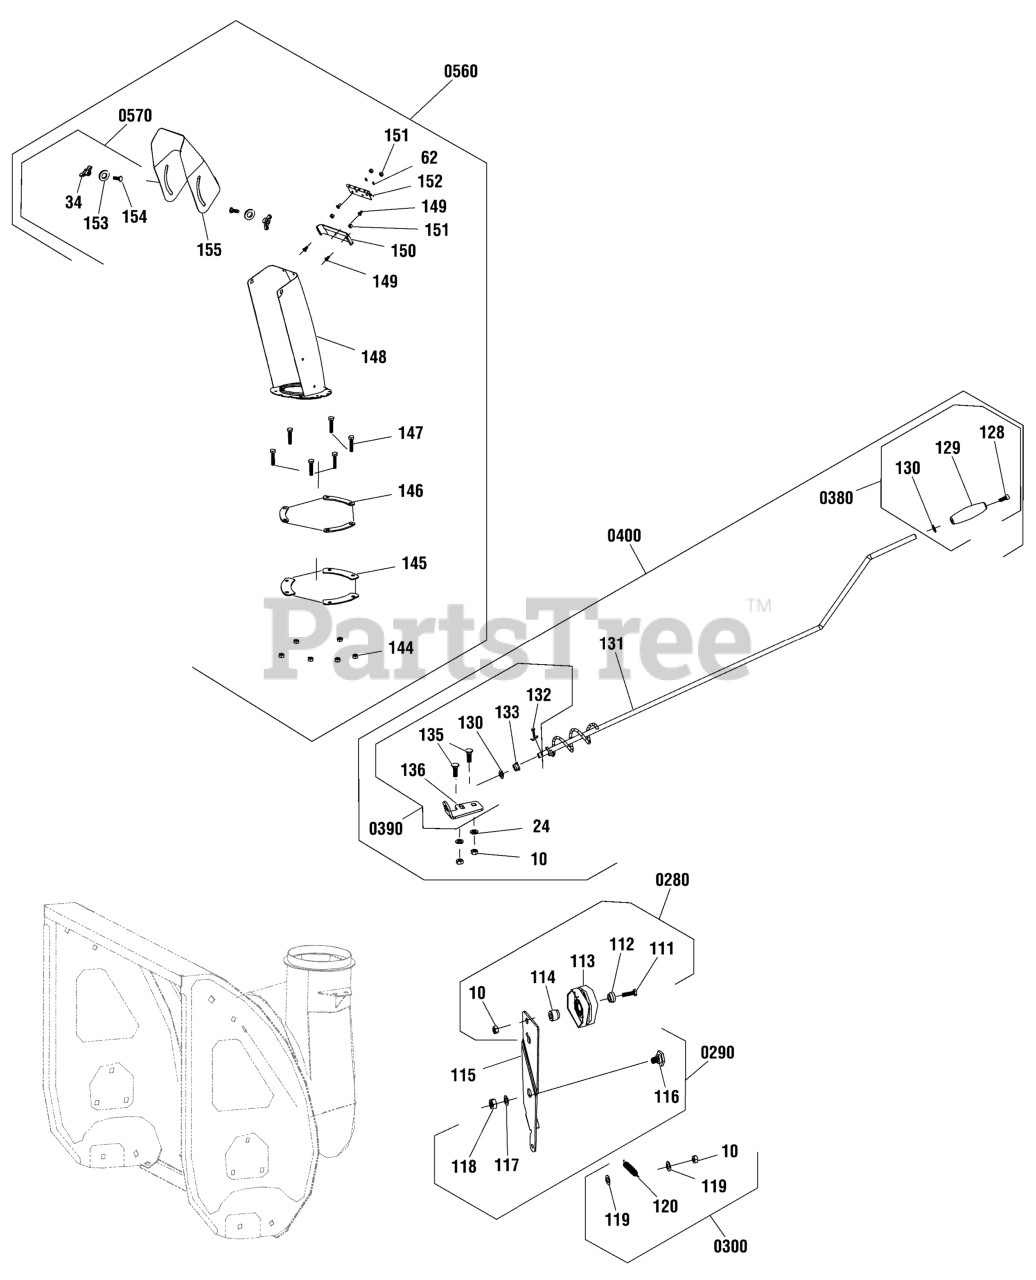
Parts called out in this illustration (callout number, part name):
10	* NUT, Lock, Hex Head, non-metal
24	* WASHER, Flat
34	* KNOB
34	* KNOB, Deflector
62	* WASHER
111	* SCREW, Hex head
112	* WASHER
113	* COVER, Large tensioning wheel
114	* SLEEVE, Washer
115	PLATE, Large tensioning
116	* BOLT, Hexagonal nut
117	* WASHER, Flat
118	* NUT, Lock, Hex Head, non-metal
119	* WASHER, Flat
120	* SPRING
128	* SCREW, Flange, Hex head
129	* GRIP, Handle, Chute Rotator
130	* WASHER, Flat
131	* ROD, Chute Rotator
132	* SPLITPIN
133	* RING, Plastic, Mounting plate
135	* BOLT, Square Neck,Cup head
135	* BOLT, Square Neck, Cup head
136	* PLATE, Mounting, Chute Rotator
144	* NUT, Lock, Hex Head, non-metal
145	* PLATE, Chute Installing
146	* GASKET, Chute Installing
147	* SCREW, Hex head
148	* WELDMENT, Lower, Chute
149	* BOLT, Phillips head
150	* PAD, Rubber, Chute
151	* NUT, Lock, Hex Head, non-metal
152	* HINGE, Chute
153	* WASHER, Flat
154	* BOLT, Square Neck, Cup head
155	* DEFLECTOR
0280	KIT-IDLER PULLEY, TENSION PLATE
0290	KIT-HARDWARE, IDLER BRACKET
0300	KIT-SPRING, IDLER PULLEY
0380	KIT-HANDLE, CHUTE ROD
0390	KIT-MOUNTING PLATE, CHUTE ROTATION
0400	KIT-CHUTE ROTATION
0560	KIT-CHUTE ASSEMBLY, RED, NA
0570	KIT-WING KNOB, CHUTE
